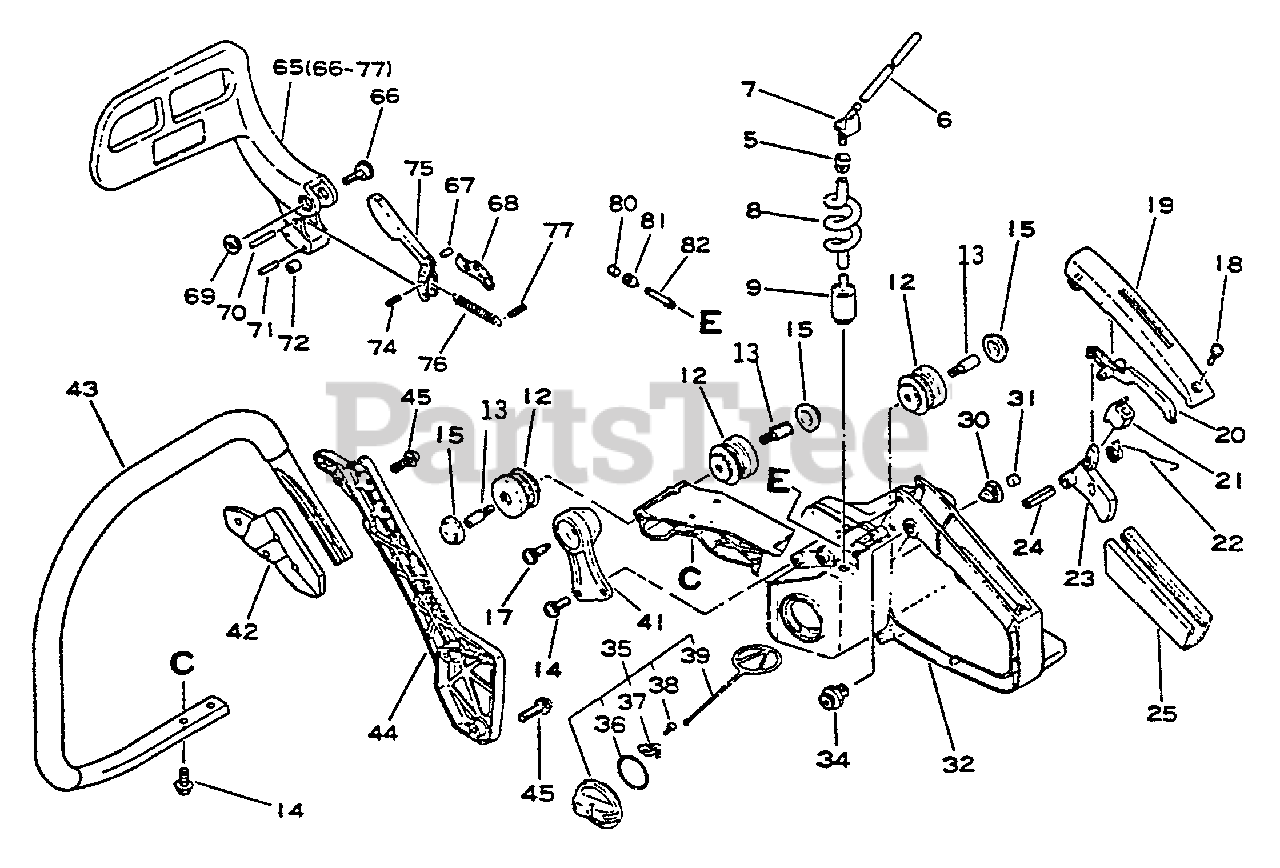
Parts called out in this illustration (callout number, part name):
5	GROMMET
6	PIPE - 3X6X100 -- BLACK
7	CONNECTOR, PIPE
8	PIPE - BLACK
9	FILTER, FUEL
12	CUSHION
13	SCREW
14	SCREW - 5X14
15	CAP, CUSHION
17	SCREW - 5X14
18	SCREW - 4X14
19	COVER, HANDLE
20	LOCKOUT, THROTTLE
22	SPRING, TRIGGER
23	TRIGGER, THROTTLE
24	PIN - SPRING -- 5X25
25	GRIP, HANDLE
32	HANDLE - REAR
34	LOCK, THROTTLE
35	CAP ASSY
36	O-RING - 29
37	RETAINER
38	SCREW - 3X8
39	CONNECTOR, CAP
41	CUSHION
42	BRACKET, HANDLE
43	HANDLE - FRONT
44	BRACKET, HANDLE - OUTER
45	SCREW - 5X20
65	BRAKE LEVER ASSY
67	PIN - LOCATING
68	STOPPER
70	PIN - 3X24
72	SPACER
74	PIN - SPRING -- 3X12
75	WEIGHT, BRAKE
76	SPRING, RETURN
77	PIN - SPRING -- 3X20
80	VENT, FUEL TANK
81	COVER, VENT
82	PIPE - VENT
83	CLIP - 5.5
84	SCREW
